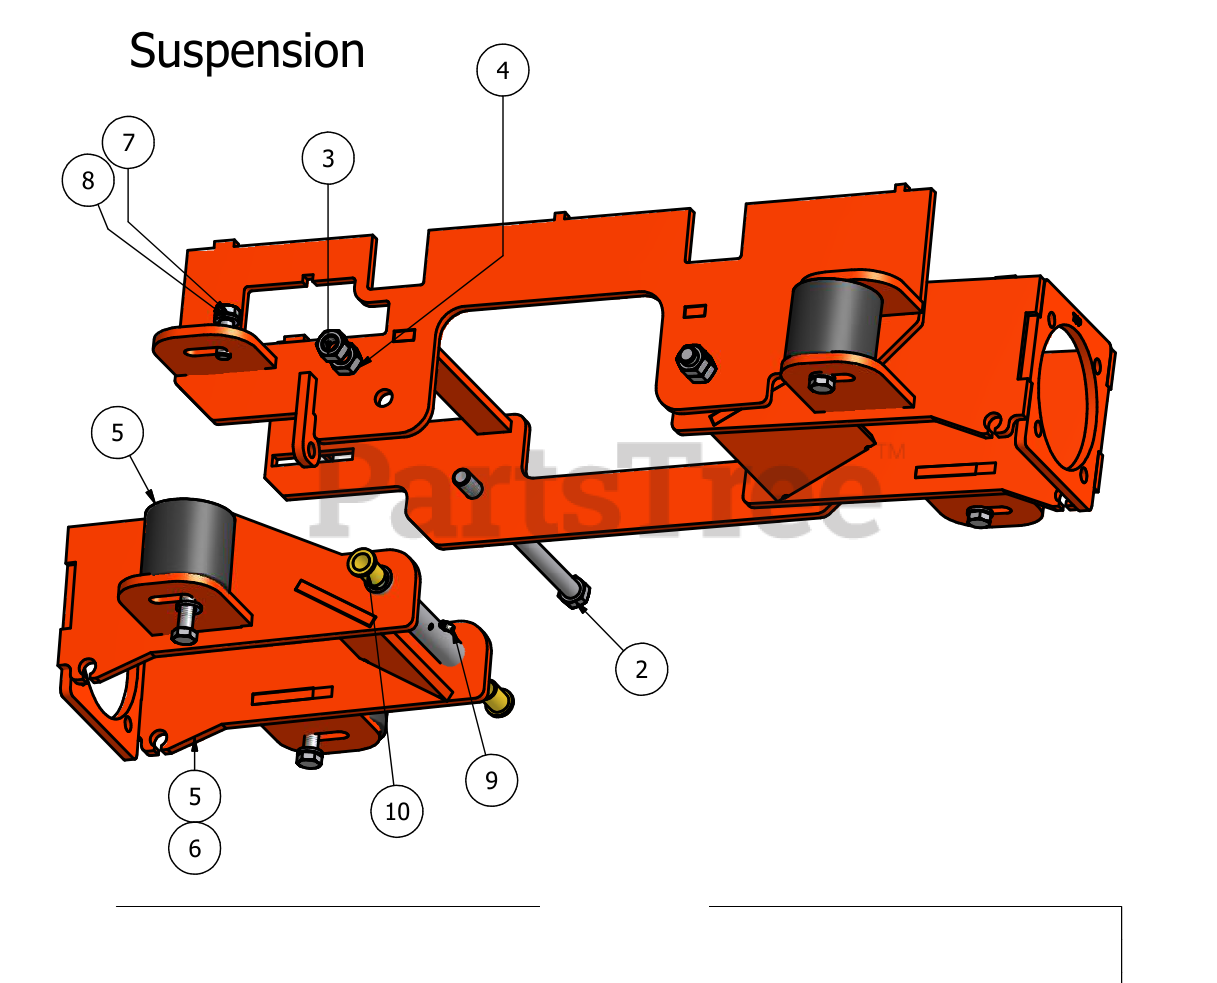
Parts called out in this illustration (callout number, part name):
1	Vibration Mount
2	5/8" x 10" Hex Bolt (Grade 8)
3	5/8" Nylock 1/2 Jam
5	60" Inner Suspension Cage
6	72" Inner Suspension Cage
7	1/2" x 1 1/2" Hex Bolt
8	1/2" Lock Washer
9	Grease Fittting (Drive-In)
10	Shoulder Spacer
11	3/4" Brass Bushing
